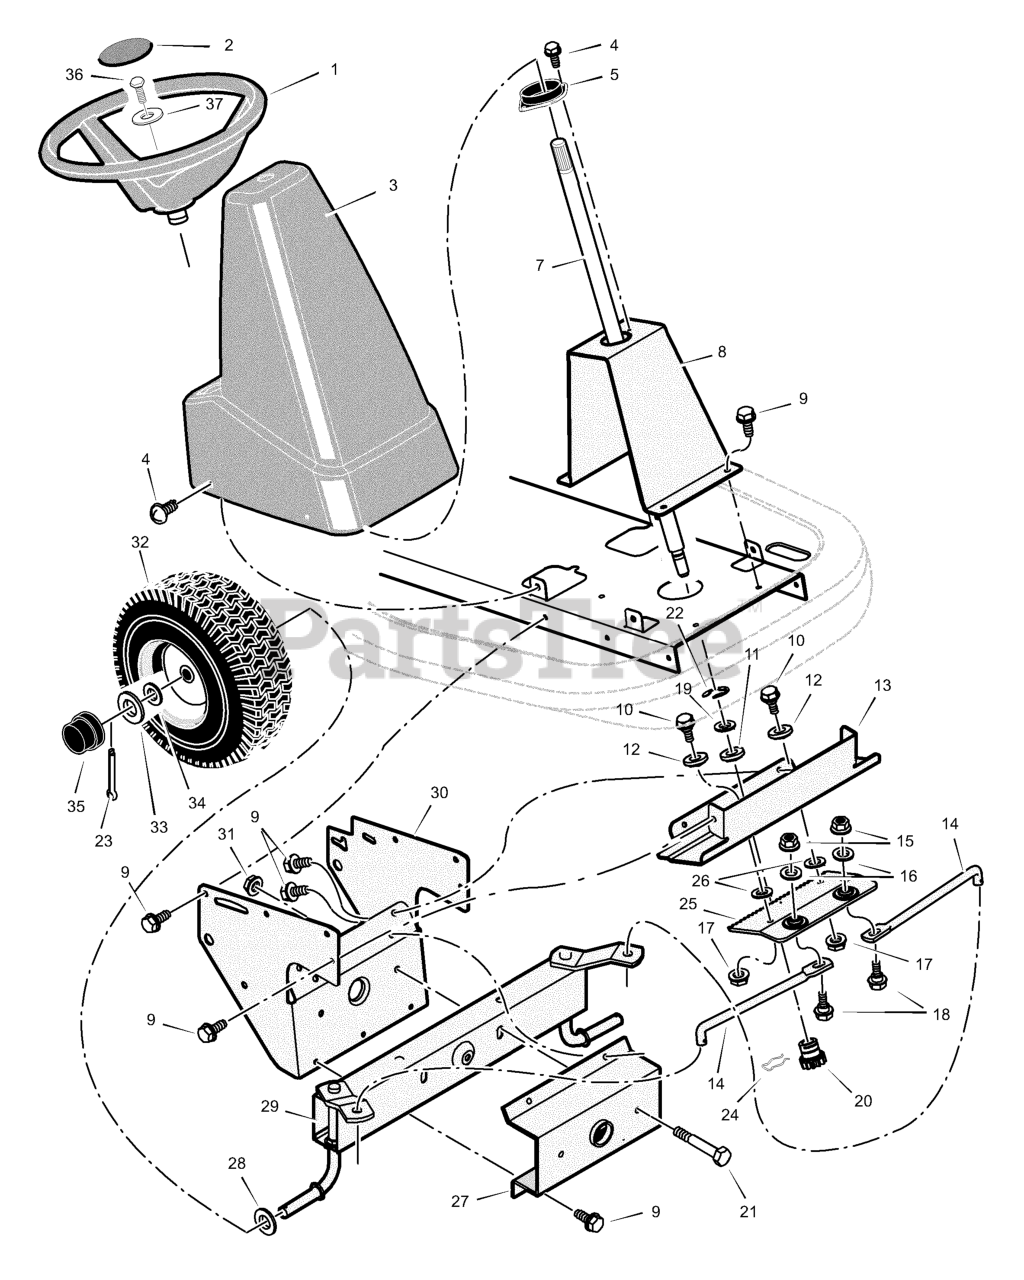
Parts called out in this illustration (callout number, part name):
1	Wheel, Steering
2	Cap, Steering
3	Console, High -Black
4	Screw
5	Bearing, Upper Steering
7	Shaft, Steering
8	Support, Steering
10	Bolt, Shoulder
11	Bearing, Lower Steering
13	Plate, Gear Mounting
14	Link, Drag
15	Nut, Flange
16	Washer
17	Nut, Flange
18	Bolt, Hex
19	WASHER, 1-1.3 16G FLT
20	Gear, Pinion
21	Bolt, Hex
22	E-Ring, Retainer
23	Pin, Cotter
24	Retainer, Spring
25	Rack, Steering
26	Washer
27	Bracket, Axle Front
28	Washer
29	Axle & Spindle Assembly
30	Bracket, Support
31	Nut, Flange
32	Wheel, Front
34	Washer
35	Cap, Hub
36	Screw, Hex
37	Washer
